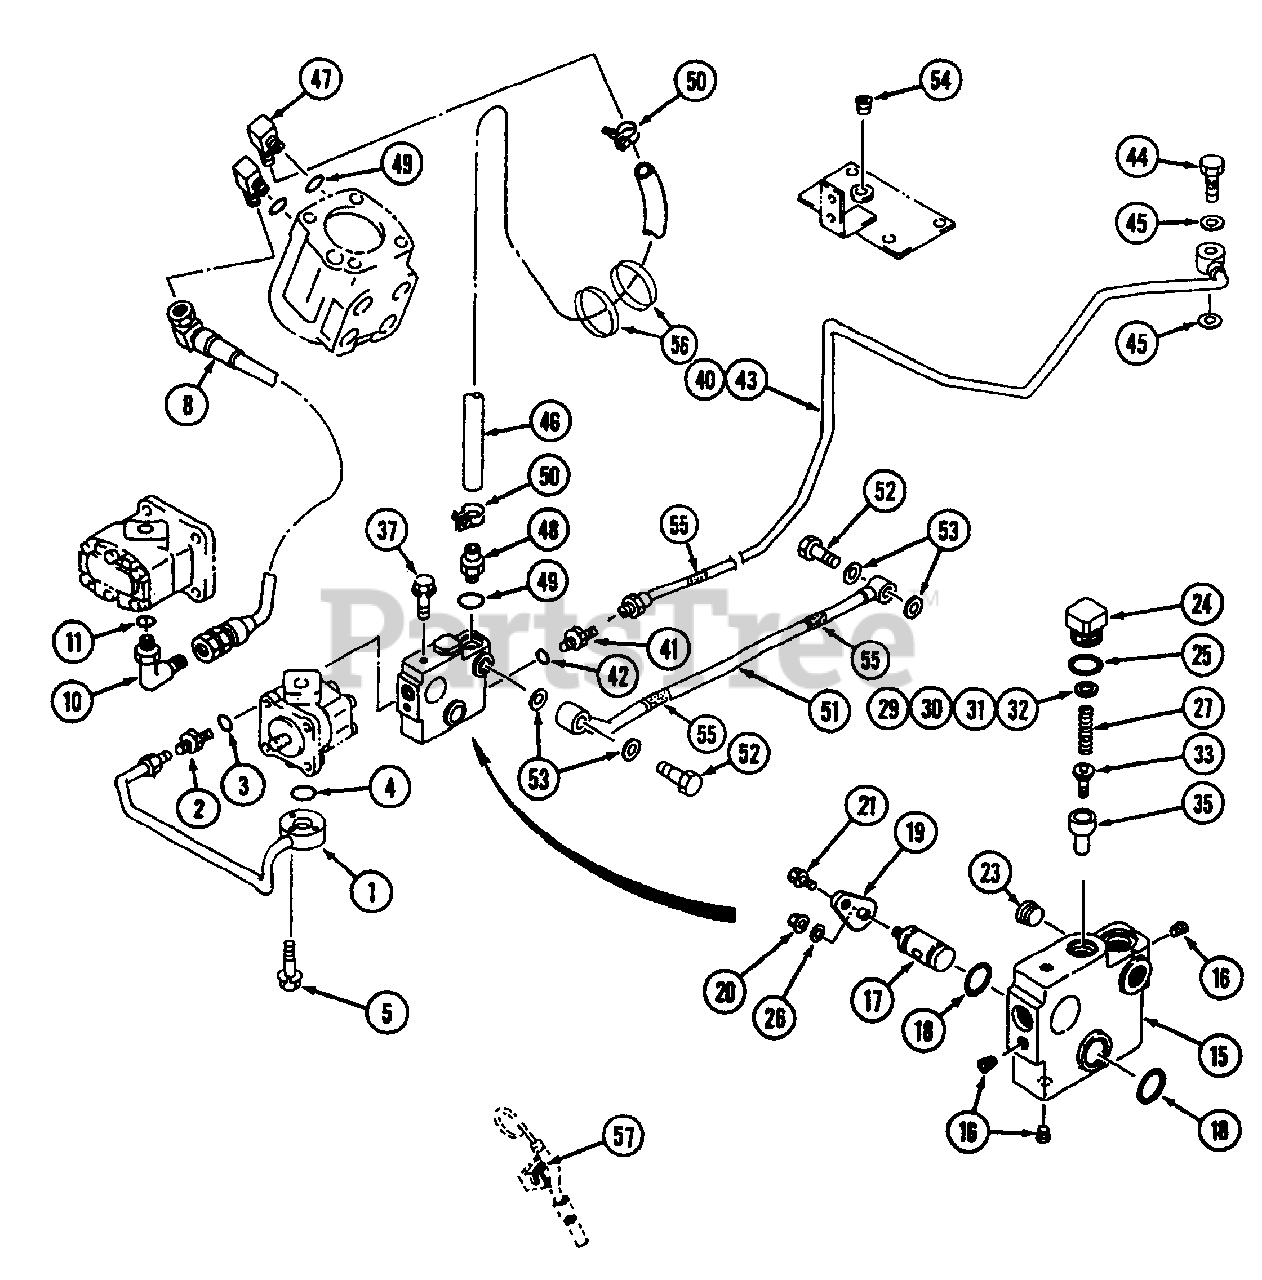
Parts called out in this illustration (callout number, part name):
1	Pipe, A Pre Ass'y.
2	Body (Nipple)
5	Bolt, W/Washer
10	Adapter
21	Bolt, W/Washer
35	Relief, Housing
37	Bolt, W/Washer
40	Pipe, C Pre Ass'y.
41	Body (Nipple)
43	Pipe, D Pre Ass'y.
45	Seal Washer
46	Hose
47	Elbow 90
48	Adapter
53	Seal, Washer
